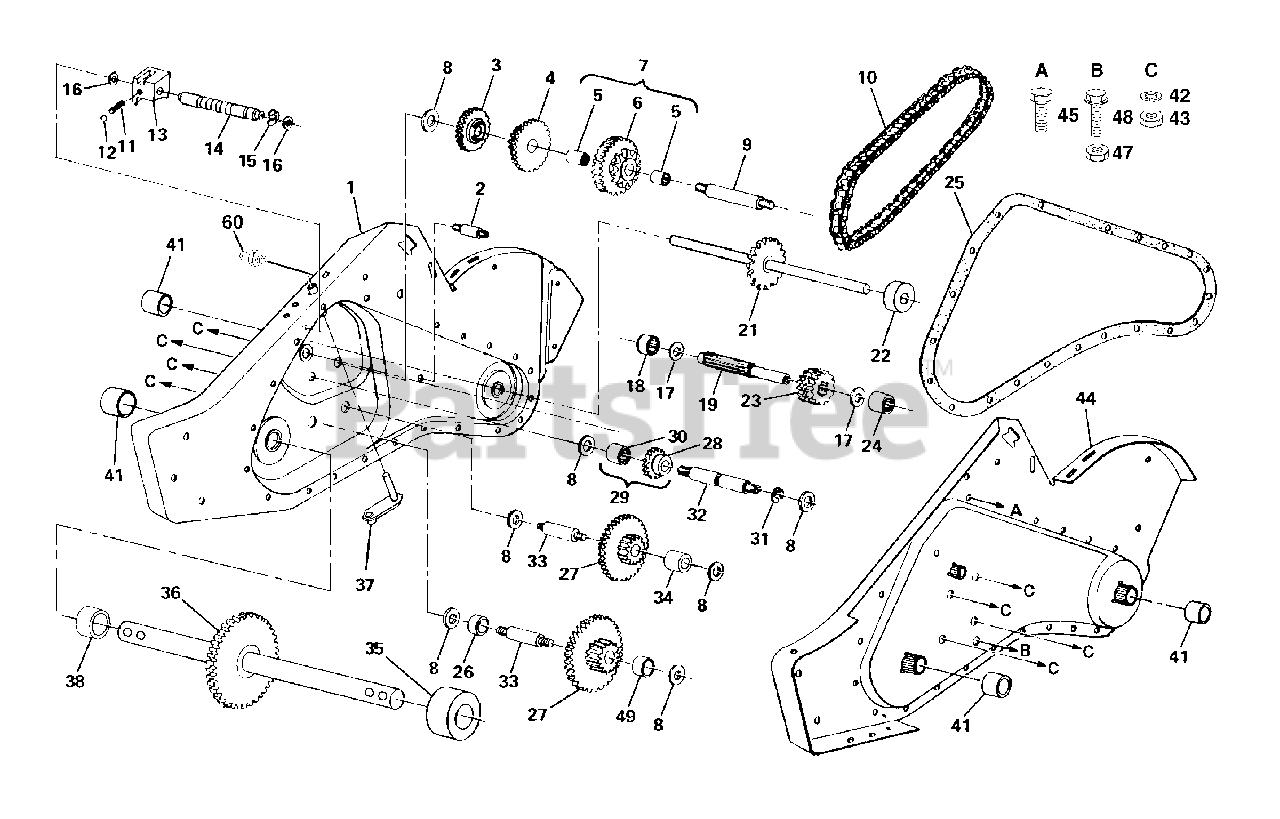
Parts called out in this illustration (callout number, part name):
1	Gearcase, R.H. w/Bearing
2	Spacer Gearcase
3	Gear Reverse
4	Gear, Cluster, Red 1st & 2nd
5	Bearing, Needle
6	Sprocket and Tine Assembly
7	Sprocket Assembly w/Bearing
8	Washer
9	Shaft, Reduction (1st)
10	Chain, Roller
11	Spring, Shift, Fork
12	Ball, Steel
13	Fork, Shift
14	Shaft, Reduction
15	Ring, Klip
16	Washer, Seal
17	Washer, Thrust 5/8 ID
18	Bearing, Needle
19	Shaft Input
21	Tine Shaft Assembly
22	Spacer 1,008 x 1-3/4 x 0,645
23	Pinion, Input
24	Bearing, Needle
25	Gasket, Gearcase
26	Spacer 0,765 I.D. x 1,12 x 5/8
27	Gear Cluster
28	Gear, Reverse Idler
29	Gear, Assembly, Reverse Idler
30	Bearing, Needle
31	Ring, Klip
32	Shaft, Reverse Idler
33	Shaft, Reduction (2nd)
34	Spacer 0,765 I.D. x 1-1/8 x 1-3/8
35	Spacer LH
36	Shaft Assembly
37	Bracket, Asm.
38	Spacer RH
41	Seal, Asm OIl
42	Push Nut 7/16
43	Nut, Hex 7/16-20
44	Gearcase, L.H. w/Bearing
45	Thread Cutting Screw 5/16-18 x 5/8
47	Nut, Hex 5/16-18
48	Screw 5/16-18 x 4
49	Spacer 0.765 ID x 1.12 x 3/4
60	Fitting, Grease
